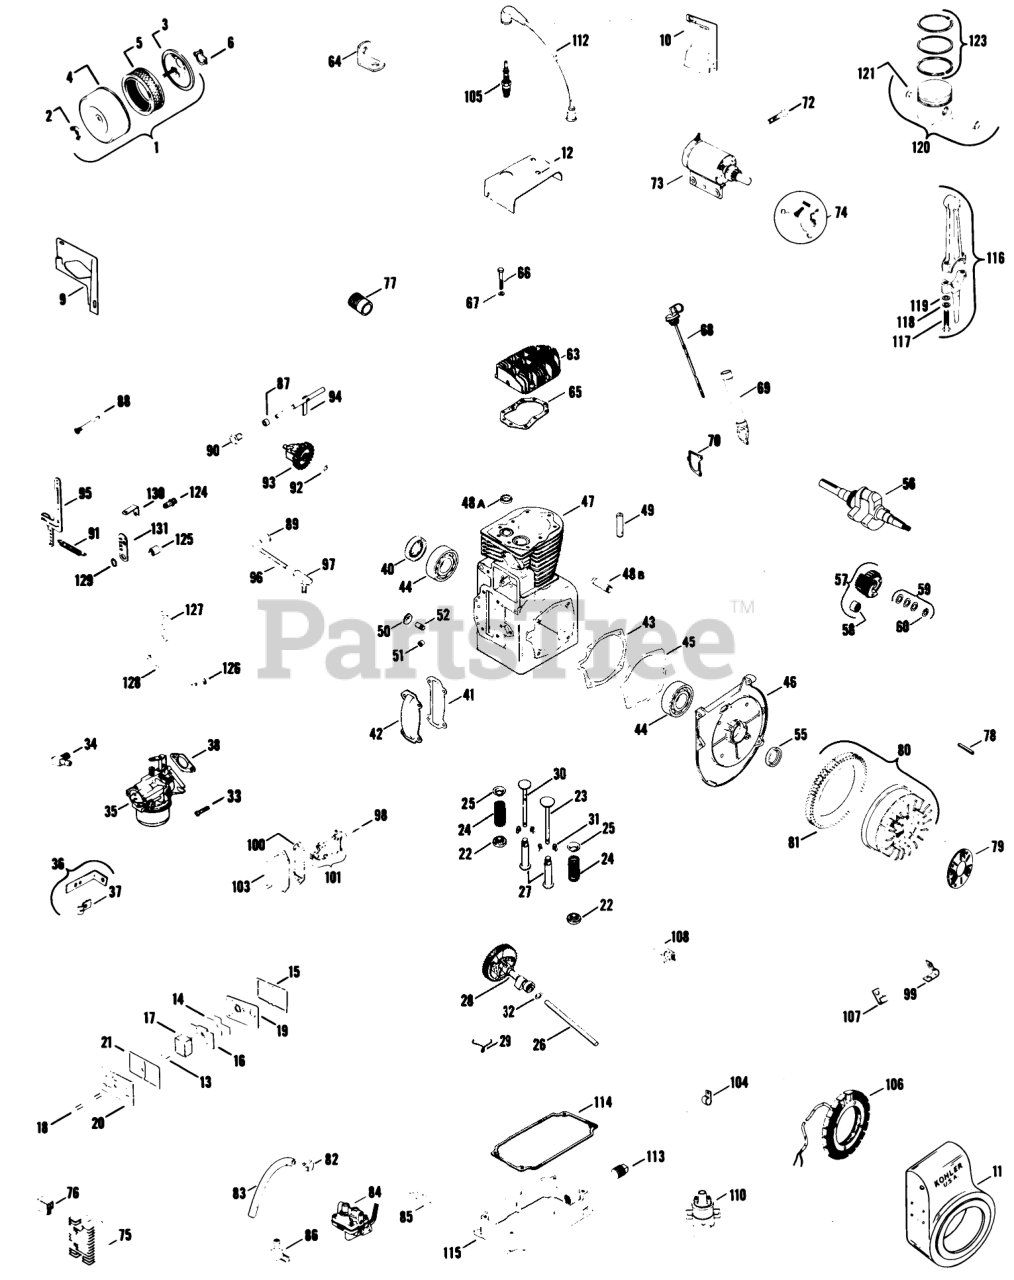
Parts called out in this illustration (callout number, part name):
1	Cleaner-Air Assembly
2	Nut-Wing
3	Base-Air Cleaner
4	Cover-Air Cleaner
5	Element
6	Gasket-Air Horn
9	BaffLe side air
10	Baffle cylinder
11	Housing-Blower
12	Baffle-Head
13	Seal
14	Reed
15	Gasket
16	Baffle breather
17	Filter Breather
18	Stud, valve cover
19	Plate
20	Cover valve
21	Gasket
22	Retainer-Spring
23	Valve-Intake
24	Spring
25	Retainer-Spring
26	Pin (Service)
27	Tappet
28	Camshaft-assembly
29	Spring-Actuating
30	Valve, exhaust
31	Keeper, Valve
32	Spacer
33	Screw sitd. hd.
34	Elbow
35	Carburetor-assembly
35	Repairkit
36	Bracket, choke
37	Clip
38	Gasket
40	Seal rear oil
41	Gasket
42	Cover
43	Gasket
44	Ball Bearing
45	Gasket
46	Plate Bearing
47	Block, cylinder-assembly (Use B-237416 Miniblock)
48A	Insert
48B	Shaft
49	Guide Valve
50	Plug
51	Bearing
52	Shaft-Govemor
55	Seal, Front OiI
56	Crankshaft
57	Gear
58	Bearing,needle
59	Kit-Spacer
60	Retainer
63	Belt Guide
64	Lift Cable
65	Gasket-Head
66	Screw
66	Screw-H.C.
67	Washer
68	Dipstick
69	Tube, fill
70	Gasket
72	Screw
73	Starter
74	Kit, Brush & Spring
75	Regulator
76	Connector
77	Washer
77	Nut
79	Screen grass
80	Flywheel-Assembly
81	Gear Ring
82	Clamp
83	Line Fuel
84	Pump, fuel
85	Gasket, pump
86	Elbow
87	Spacer
88	Pin-GovemorStop
89	Retainer Rod
90	Bushing
91	Spring-Governor
92	Washer
93	Gear, Governor
94	Shaft, Governor
95	Lever, Governor
96	Rod ball joint
97	Ball Joint
98	Rod, breaker
99	Clip
100	Gasket, Cover
101	Breaker
103	Cover breaker
104	Clip
105	Plug, spark
106	Stator
107	Clip
108	Condenser
110	Coil
112	Kit, Hi-Tension
113	Plug
114	Gasket
115	Base, oil pan
116	Rod, Connecting
117	Screw, connecting rod
118	Washer
119	Washer
120	Piston-assembly (Std.)(Includes pin & retainers)
120	Piston-assembly (.003)(Includes pin & retainers)
120	Piston-assembly (.010)(Includes pin & retainers)
120	Piston-assembly (.020)(Includes pin & retainers)
120	Piston-assembly (.030)(Includes pin & retainers)
121	Pin, Retainer
123	Ring set-Std. & .003 (Svc.)
123	Ring set-.010 (Service)
123	Ring set-.020 (Service)
123	Ring set-.030 (Service)
124	Clamp, swivel wire
125	Spacer
126	Retainer Rod
127	Bellcrank
128	Rod, throttle
129	Washer
130	Spacer
131	Bracket
131	Gasket Set
131	Miniblock
131	Short Block
131	Service Engine
